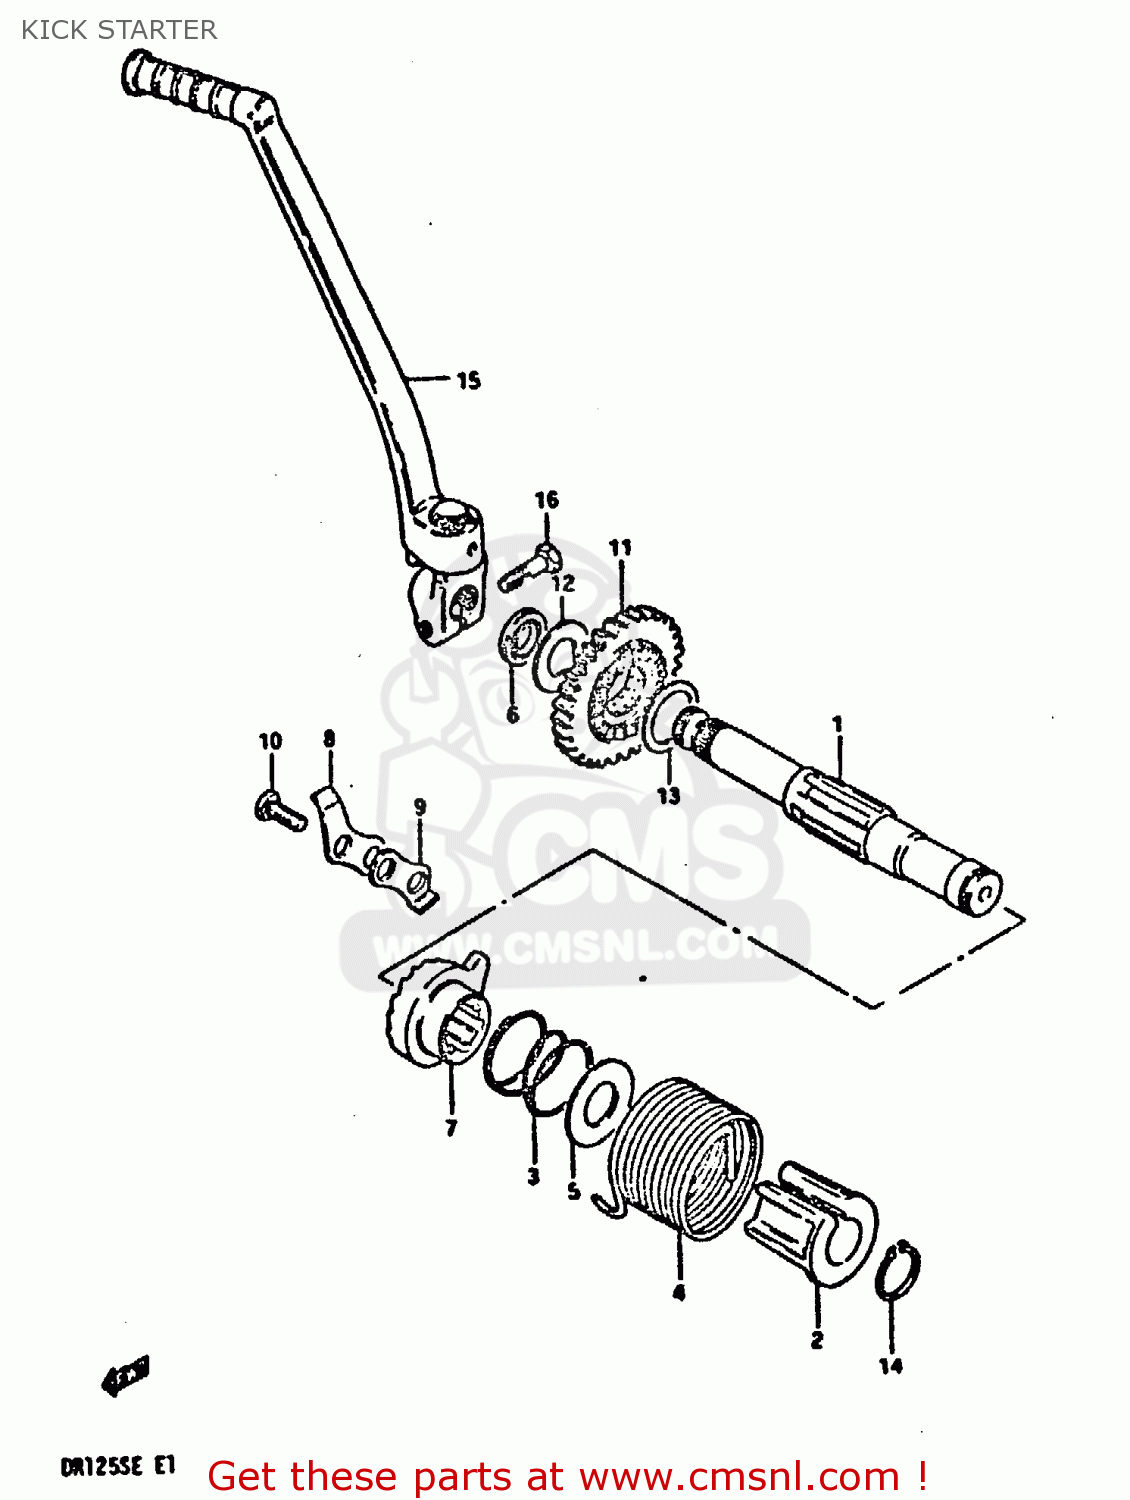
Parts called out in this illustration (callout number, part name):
1	SHAFT,KICK STARTER
2	GUIDE,KICK STARTER SFT SPRING
3	SPRING
4	SPRING
5	WASHER
6	SEAL,OIL(16X24X5)
7	STARTER,KICK
8	GUIDE,KICK STARTER
9	STOPPER,KICK STARTER
10	BOLT
11	GEAR,KICK STARTER DRIVE
12	WASHER(16X30X1)
13	WASHER
14	CIRCLIP
15	LEVER ASSEMBLY,KICK STARTER
16	BOLT 8X25
